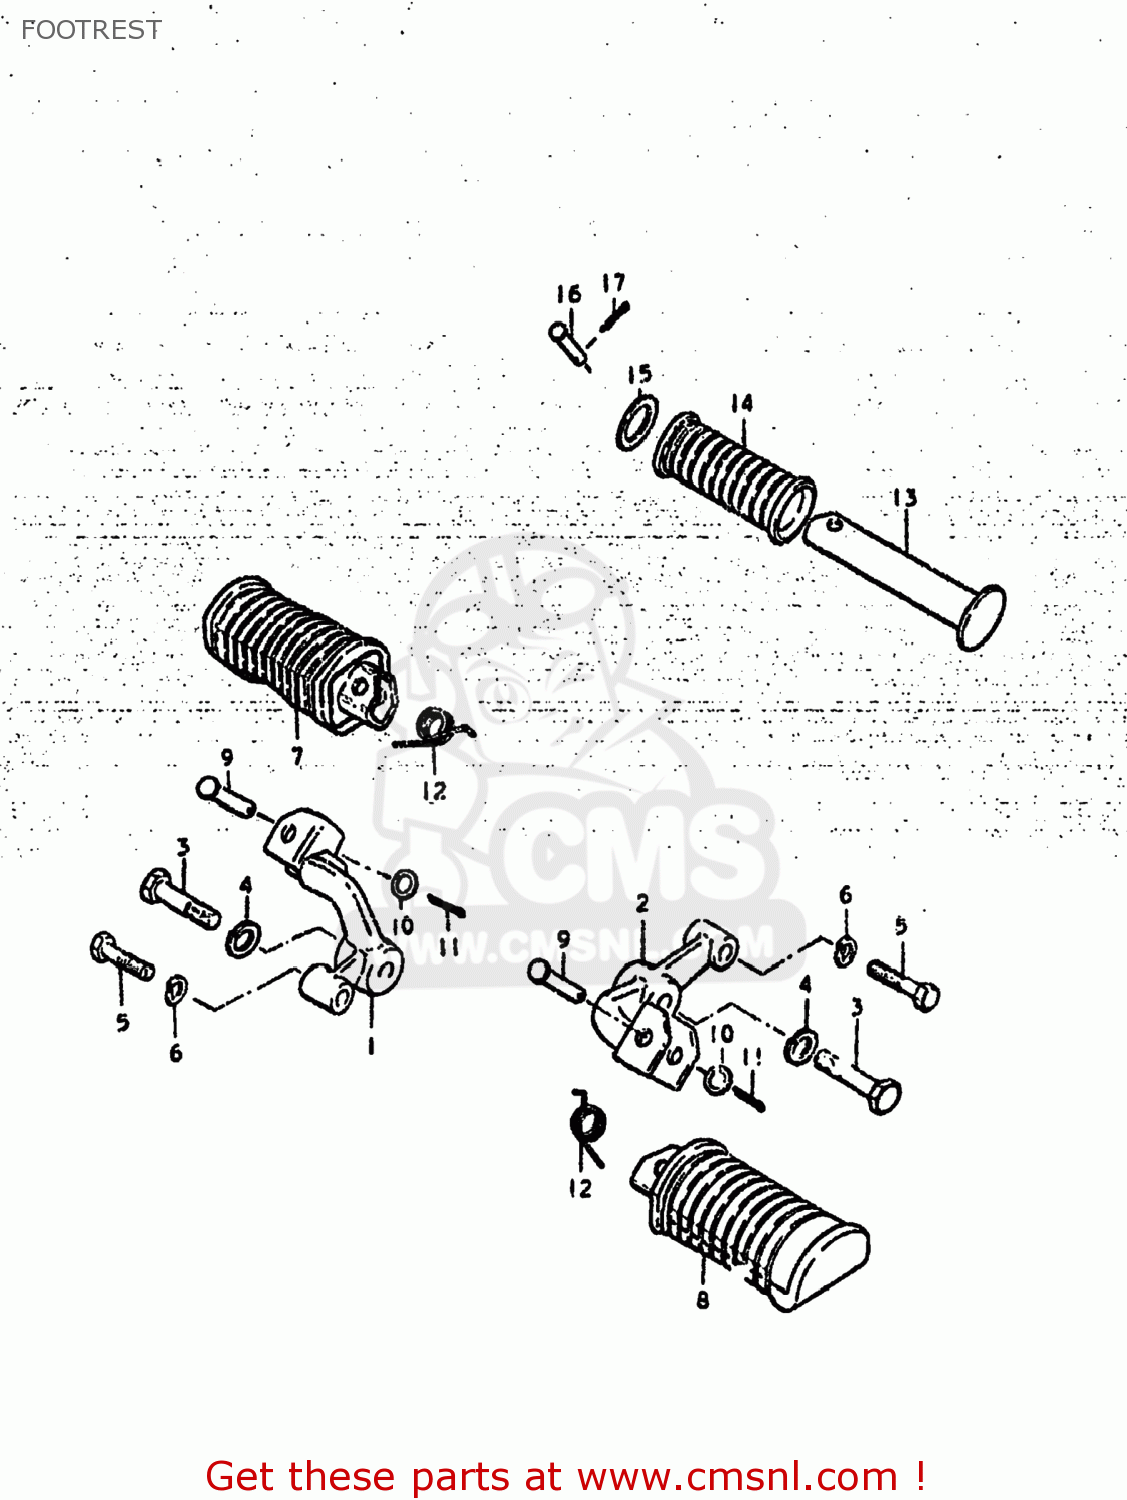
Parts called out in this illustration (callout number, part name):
1	BAR,FRONT FOOTREST
2	BAR,FRONT FOOTREST,LEFT
3	BOLT
4	LOCK WASHER
5	BOLT 8X40
6	WASHER,LOCK
7	RUBBER,FRONT FOOTREST
8	FOOTREST
9	PIN
10	WASHER
11	PIN 20X20
12	SPRING
13	BAR,FOOTREST RUBBER
14	RUBBER,PILLION FOOTREST
15	WASHER (19.5X32X2)
16	PIN
17	PIN
